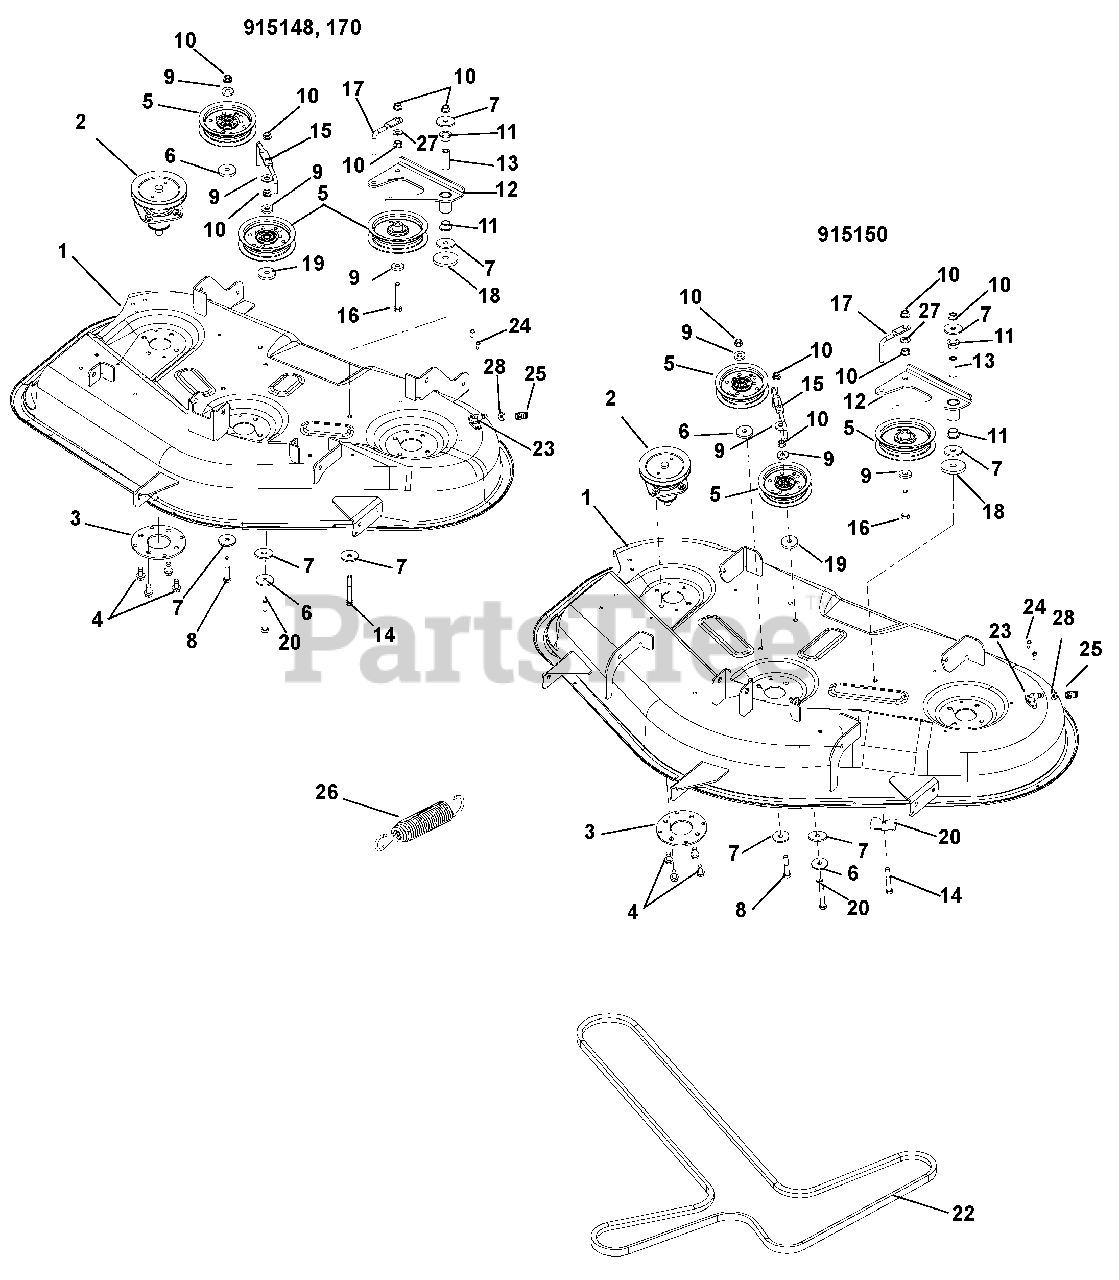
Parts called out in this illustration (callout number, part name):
1	Kit, Gravely 42" Deck with Decals (915148, 170)
1	Kit, Gravely 50" Deck with Decals (915150)
2	Assembly, Spindle (915148, 170)
2	Assembly, Spindle (915150)
3	Plate, Spindle
4	Screw, Tapping .38-16 x .75 Hex Washer Head
5	Assembly, Idler 4"
6	Washer, Flat Steel .406 x 1.50 x .245
7	Washer, Flat Steel .380 x 1.50 x .125 (915148, 170)
7	Washer, Flat Steel .380 x 1.50 x .125 (915150)
8	Bolt, Hex .38-16 x 2.25
9	Washer, Flat Steel .406 x 1.00 x .188
10	Nut, Locking Top Flange .38-16
11	Bushing, Flange, .625 x .750 x .500 x 1.00
12	Idler Arm
13	Spacer, .375ID x .625 OD x 1.66
14	Bolt, Hex .38-16 x 3.00
15	Belt Finger
16	Bolt, Hex .38-16 x 2.25
17	Wireform Belt Finger
18	Washer, Flat Steel .469 x 2.00 x .25
19	Washer, Flat Steel .438 x 1.00 x .083
20	Bolt, Hex .38-16 x 2.75
21	Plate, Deck (915150)
22	V-Belt, 4L Wrapped (915148, 170)
22	V-Belt, 4L Wrapped (915150)
23	Assy, Washout Port W/O Ring
24	Screw, Tapping .25-20 x .62 Hex Washer Head Thread Rolling
25	Coupling, Quick Disconnect
26	Extension Spring .135 x .98 x 6.0
27	Washer, Flat Steel .406 x .812 x .065
28	O-Ring .362 X .103 X .568
